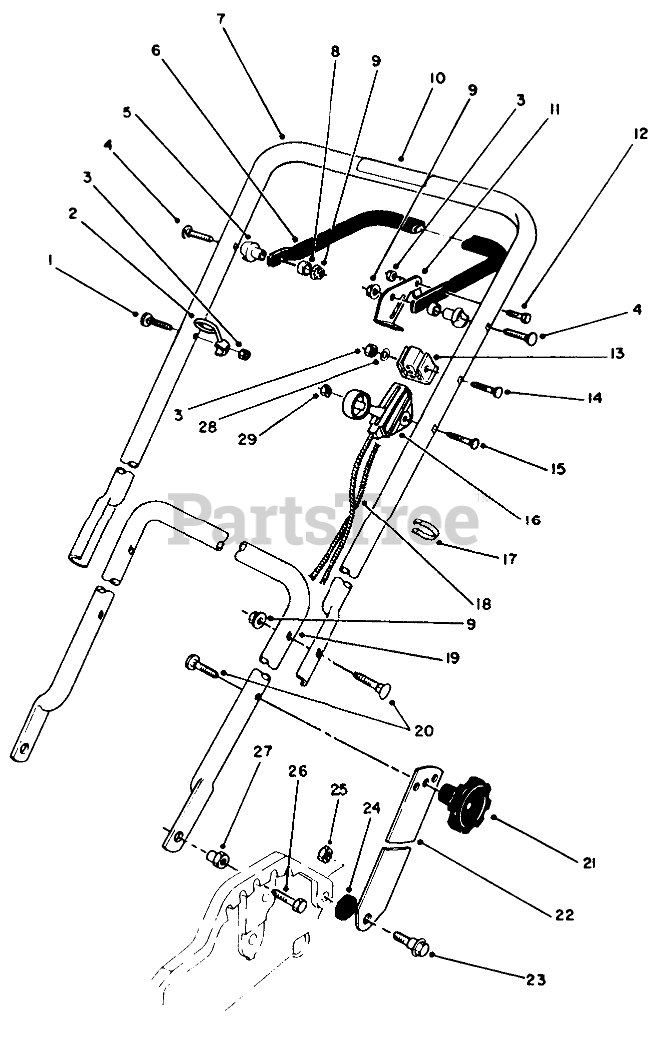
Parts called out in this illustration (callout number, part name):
1	HANDLE SCREW
2	Guide
3	NUT-LOCK, NI
4	5/16-18 X 2 HNDLE SCREW
5	SPACER-SUPPORT
6	Bar-Control
7	Handle-Upper (Incl. Ref. #10)
8	SPACER-NYLON
9	NUT-LOCK, NI
10	Decal-Danger
11	LEVER-CONTROL
12	SCREW-HH
13	SUPPORT-CABLE
14	HANDLE SCREW
15	SCREW-HANDLE
16	THROTTLE CONTROL
17	BOWDEN CLIP
18	BRAKE CABLE
19	LOWER HANDLE
20	SCREW
22	Handle Latch
23	SCREW-SHOULDER
24	SPACER
25	NUT-LOCK, NI
26	SCREW-HH
27	HANDLE PIVOT NUT
28	WASHER-FLAT
29	NUT-LOCK, NI
